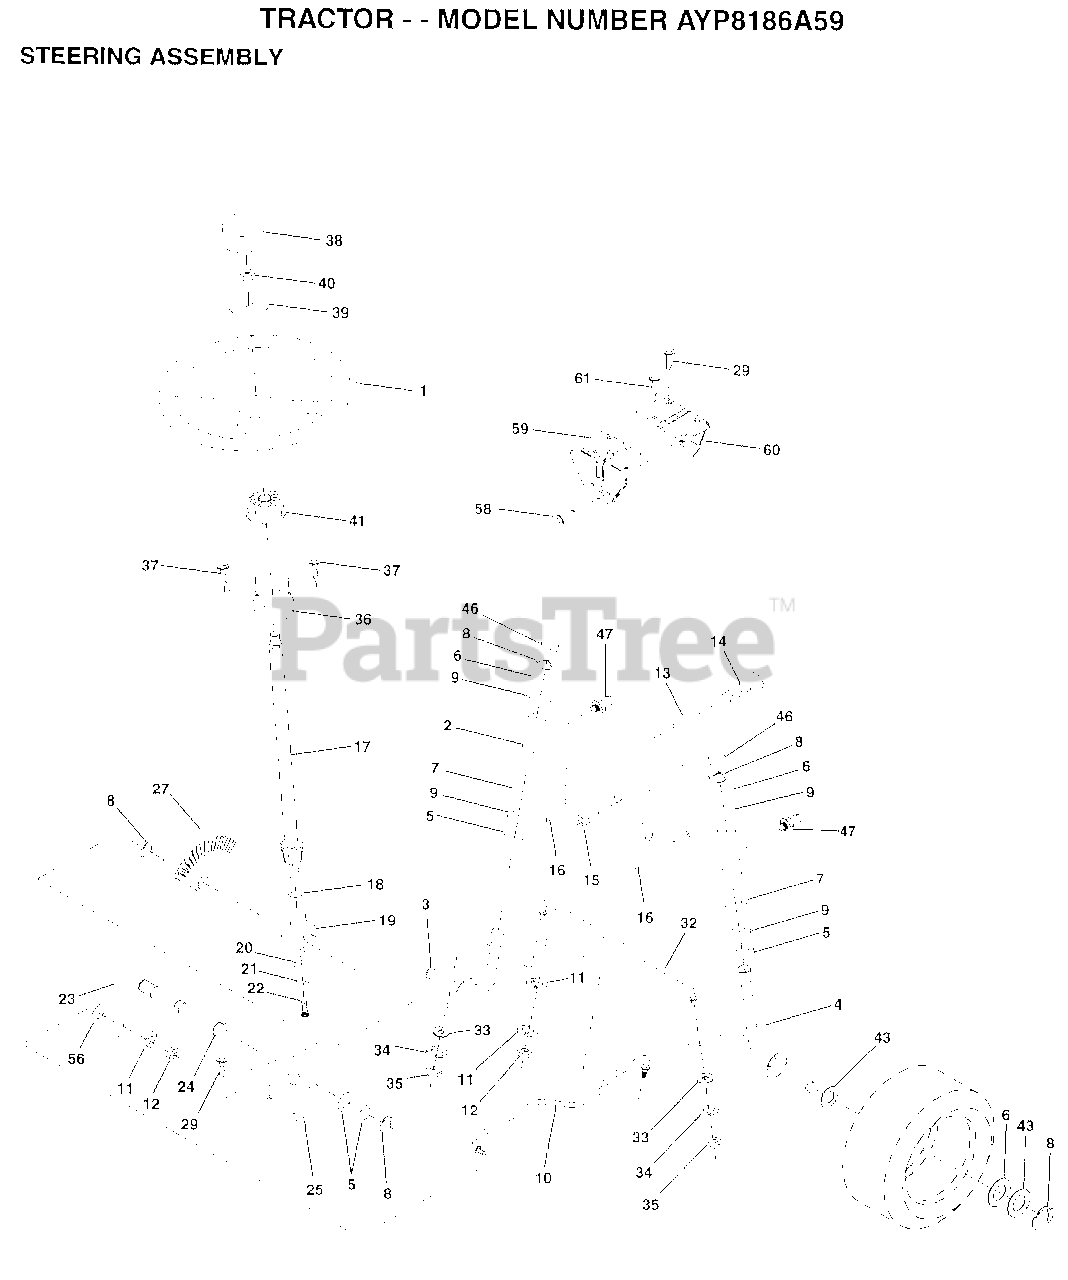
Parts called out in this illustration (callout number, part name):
2	AXLE ASM FRONT
5	WASHER .T
6	WASHER
7	WASHER
8	RING
9	COL. SRTG. BEAR.
11	LOCKWASHER
13	BEARING
14	BOLT LT
15	"NUT-LOC,FLANGE LT"
16	AXLE PIN
17	STEERING SHAFT
18	THRUST WASHER
19	SUPPORT.SHAFT
21	LOCKWASHER
22	"SCREW,SPECIAL"
24	NYLINER T
25	"BRKT,STEERING"
27	GEAR SECTOR
29	SCREW
32	TIE ROD
33	WASHER M
34	LOCKWASHER
35	NUT.LOCK.5/16-24
36	BUSHING.STRG.3/4
37	SCREW.10-24X1/2
38	ST WHL INSERT CAP
39	WASHER
41	ADAPTER LT
43	WASHER
46	CAP
47	ZERK M
56	WASHER
58	SCREW LT
59	SUPPORT-SADDL T
60	SUPPORT.SADDLE.FT
